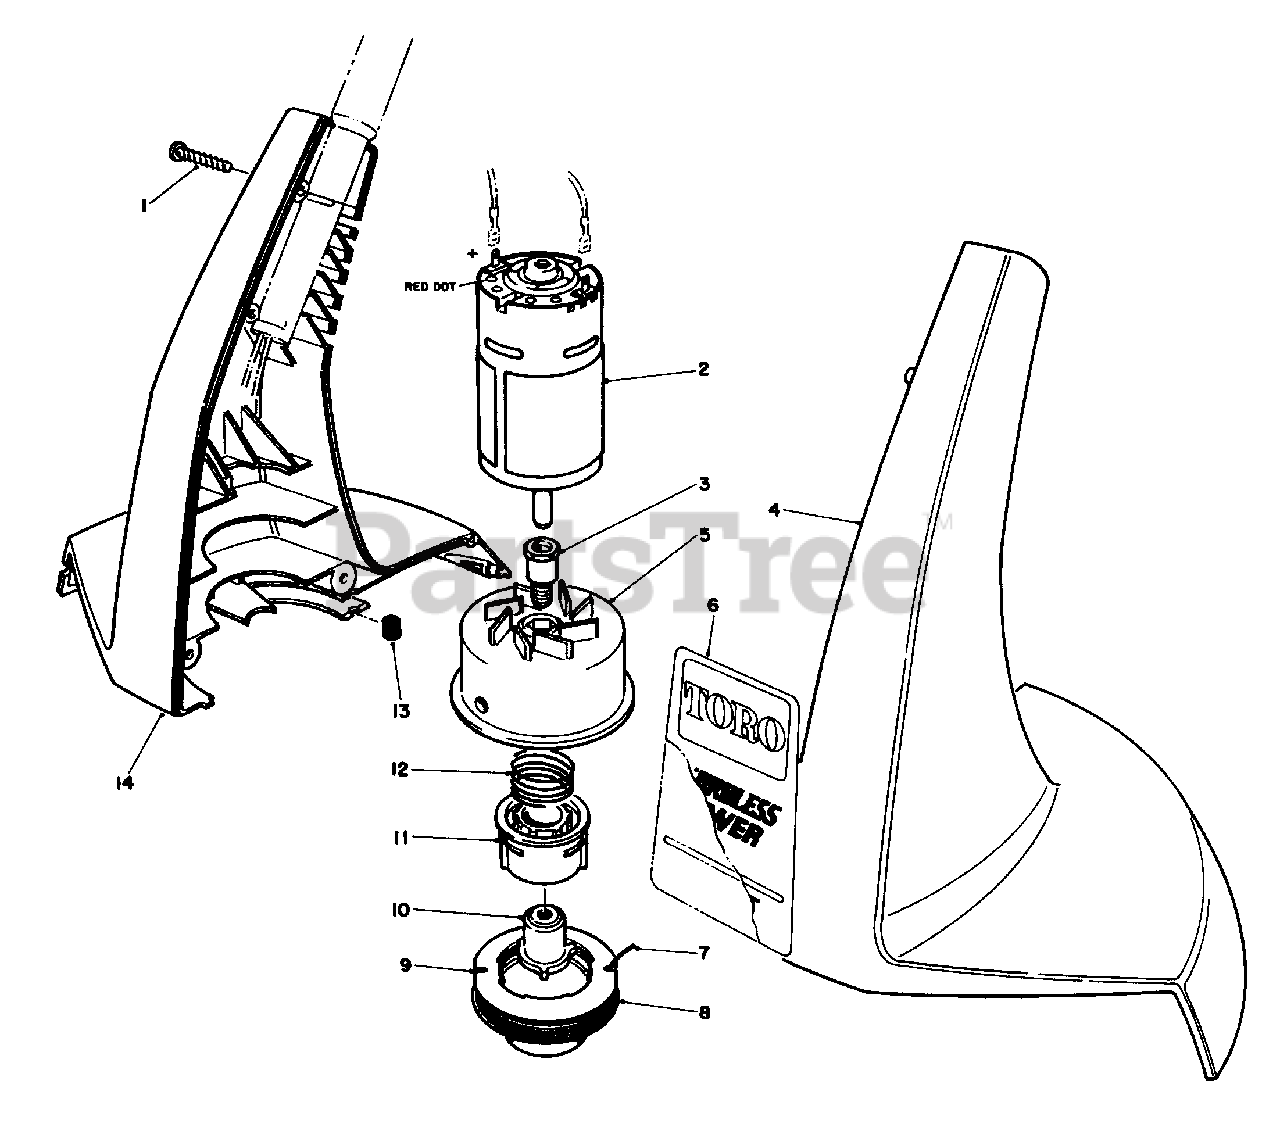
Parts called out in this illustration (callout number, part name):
1	Screw-Thread Forming
2	Motor Assembly (Incl. Ref. #3)
3	Extension-Shaft
4	Housing-L.H.
5	Drum-Assembly
8	Pre-wound Spool (Incl. Ref. #7 & 9)
9	Spool-Cup
11	Core-Spool
12	Spring-Compression
14	Housing-R.H.
